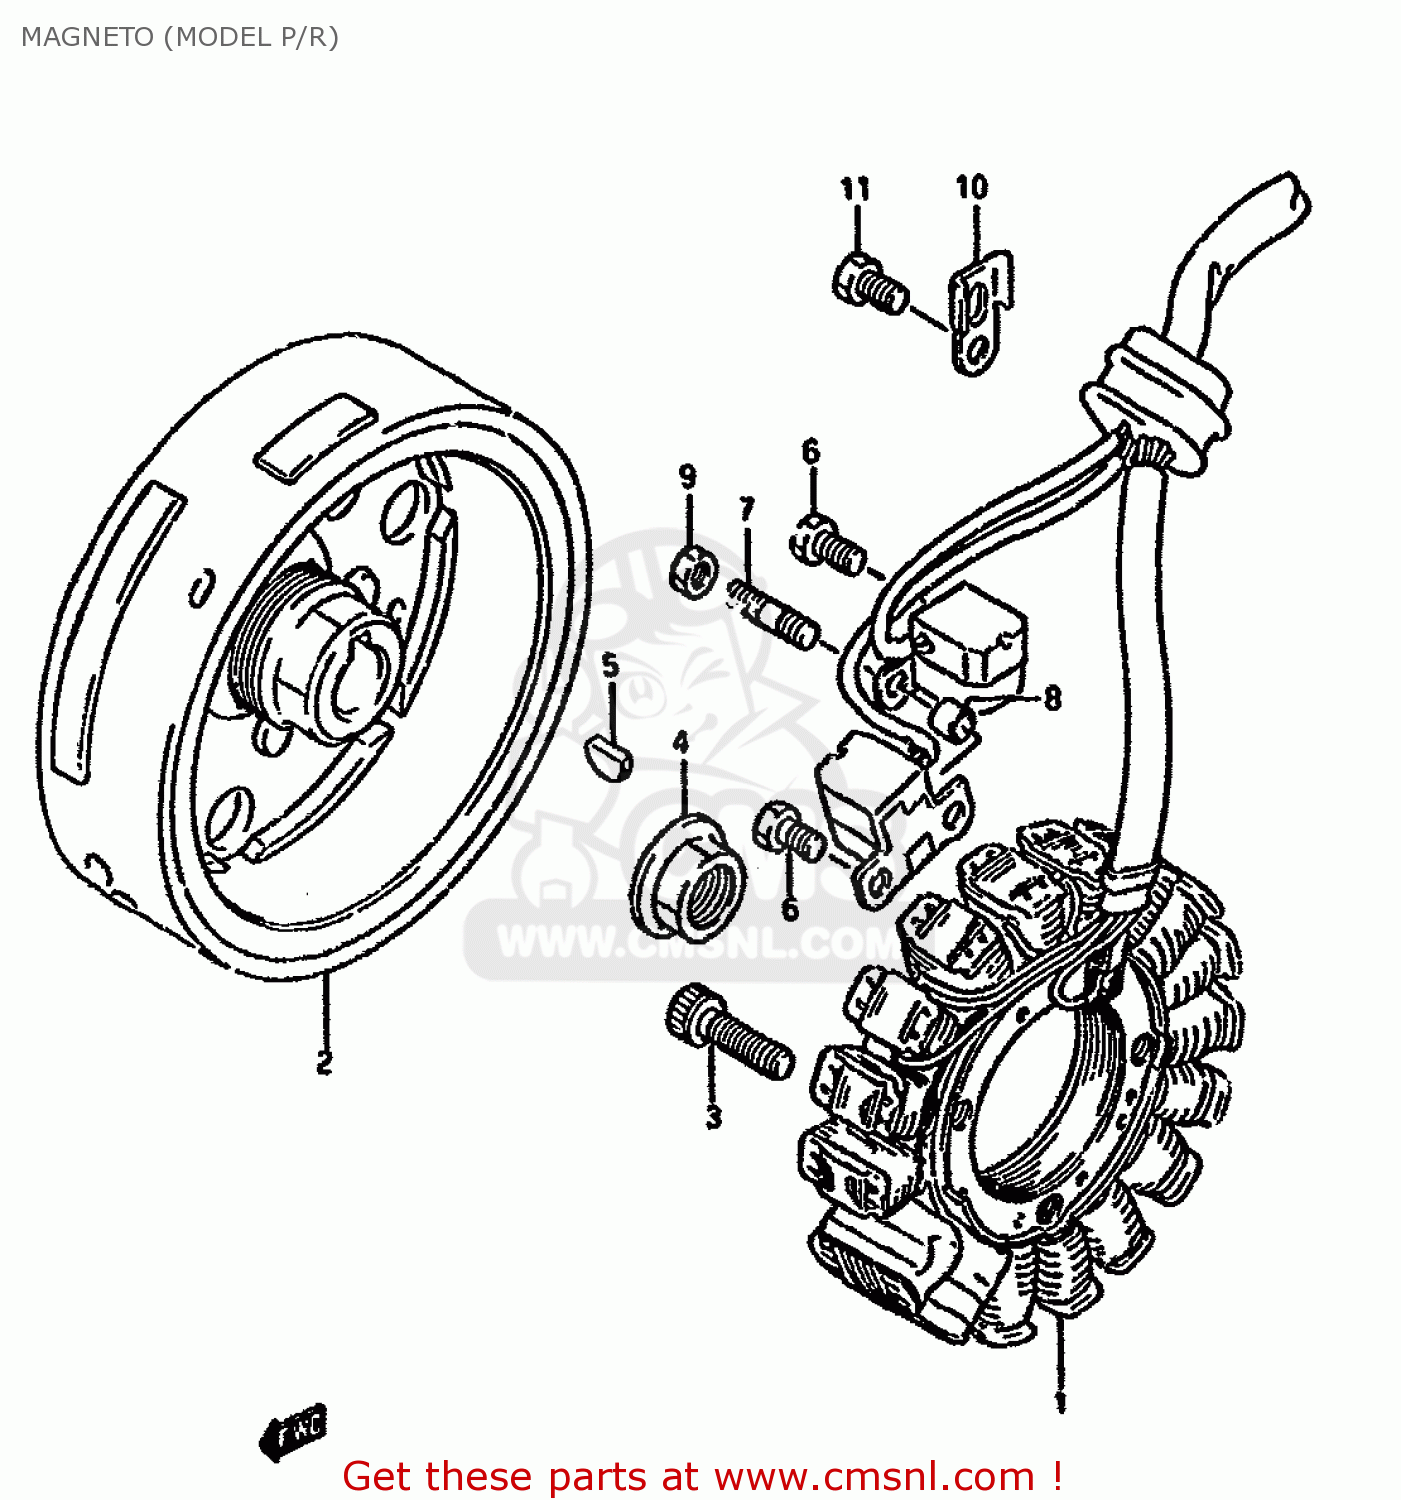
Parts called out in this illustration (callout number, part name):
1	STATOR ASSEMBLY
2	ROTOR
3	BOLT
4	NUT
5	KEY
6	BOLT(5X10)
7	BOLT,STUD(5X18)
8	SPACER (5.5X9.5X6.5)
9	NUT
10	CLAMP,GENERATOR LEAD WIRE
11	BOLT(5X10)
